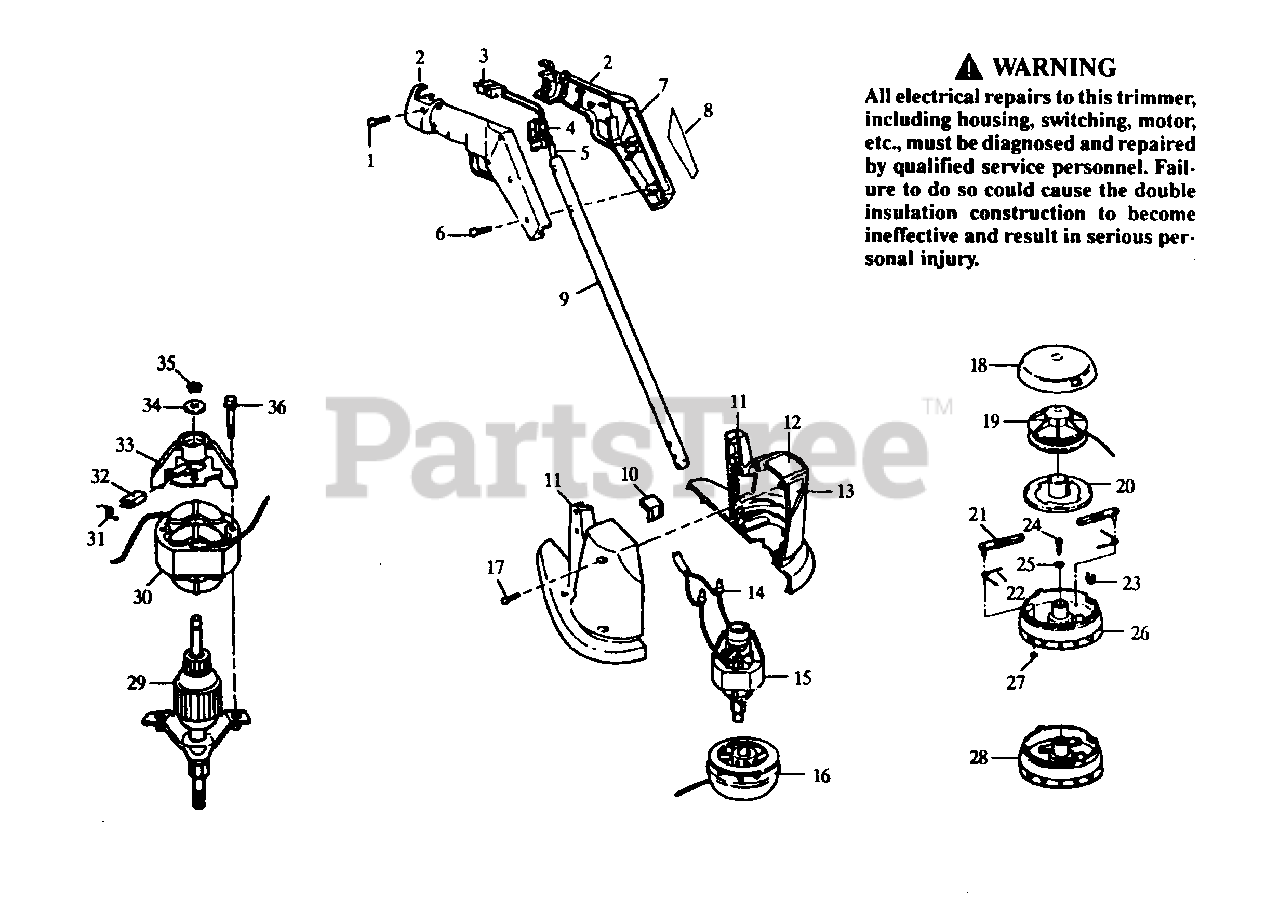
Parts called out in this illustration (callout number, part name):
2	Handle Set
4	Trigger Switch
7	Handle Label (Not a serviceable part)
8	Warning Label (Not a serviceable part)
10	Line Cutter
11	Housing Set
12	Housing Top Label (Not a serviceable part)
13	Housing Front Label (Not a serviceable part)
14	Terminal Cap
15	Motor/Adapter Ass'y.
16	Cutting Head Ass'y.
19	Spool w/Line
23	Line Shield
26	Housing/Baffle Ass'y.
27	Push Nut
28	Housing Ass'y. (Incl. 21-23,26,27)
29	Armature/Endbell Ass'y.
30	Field Ass'y.
31	Brush Spring
32	Carbon Brush
33	Bracket/Plate Ass'y.
34	Washer, Shim
35	Retaining Ring
